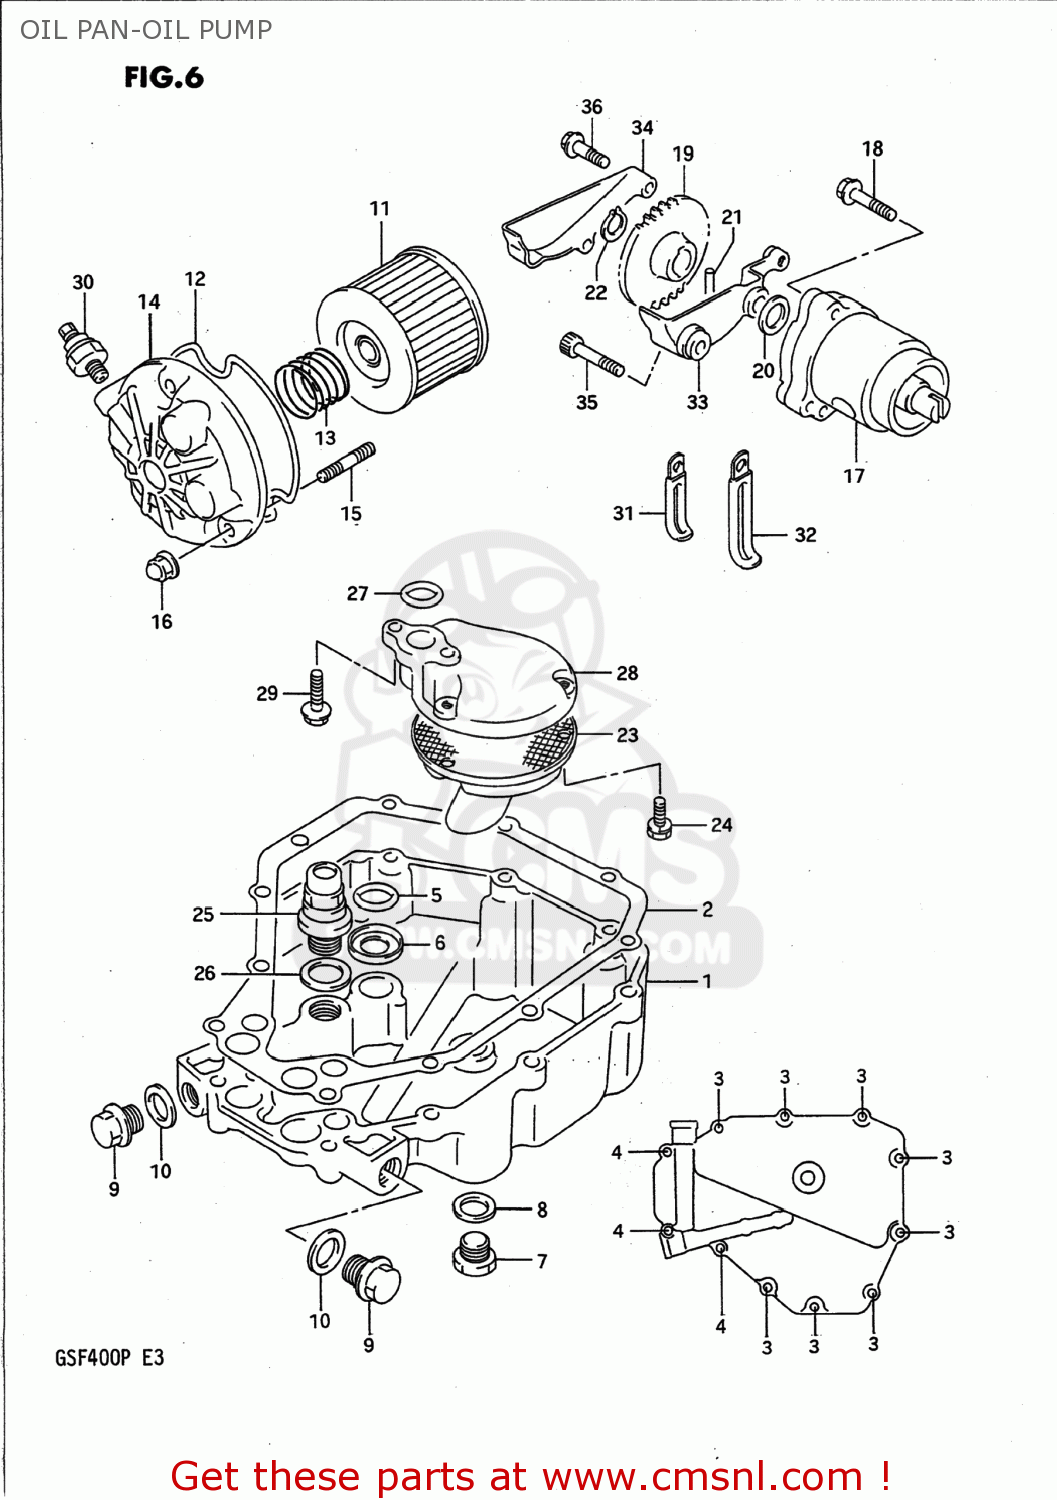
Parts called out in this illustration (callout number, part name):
1	PAN,OIL
2	GASKET,OIL PAN (NAS)
3	BOLT 6X25
4	BOLT 6X30
5	O RING(D:3.2,ID:15.8)
6	GASKET,OIL OUTLET (NAS)
7	PLUG
8	GASKET(14X19.2X2) (NAS)
9	PLUG(14X12)
10	GASKET(14X19.2X2) (NAS)
11	FILTER ASSY,ENGINE OIL
12	O RING,OIL FILTER CHAMBER CAP
13	SPRING
14	CAP,FILTER
15	STUD 6X20
16	NUT 6MM
17	PUMP ASSY,ENGINE OIL
18	BOLT
19	GEAR,OIL PUMP DRIVEN
20	SHIM
21	PIN(5X18)
22	CIRCLIP,12 MM
23	STRAINER,ENGINE OIL
24	BOLT
25	VALVE ASSY,OIL RELIEF
26	GASKET(16X22X2) (NAS)
27	O RING(D:3.2,ID:15.8)
28	PROTECTOR,OIL STRAINER
29	BOLT 6X20
30	SWITCH ASSEMBLY
31	CLAMP
32	CLAMP
33	CASE,OIL SEPARATOR
34	CAP,OIL SEPARATOR
35	BOLT
36	BOLT
